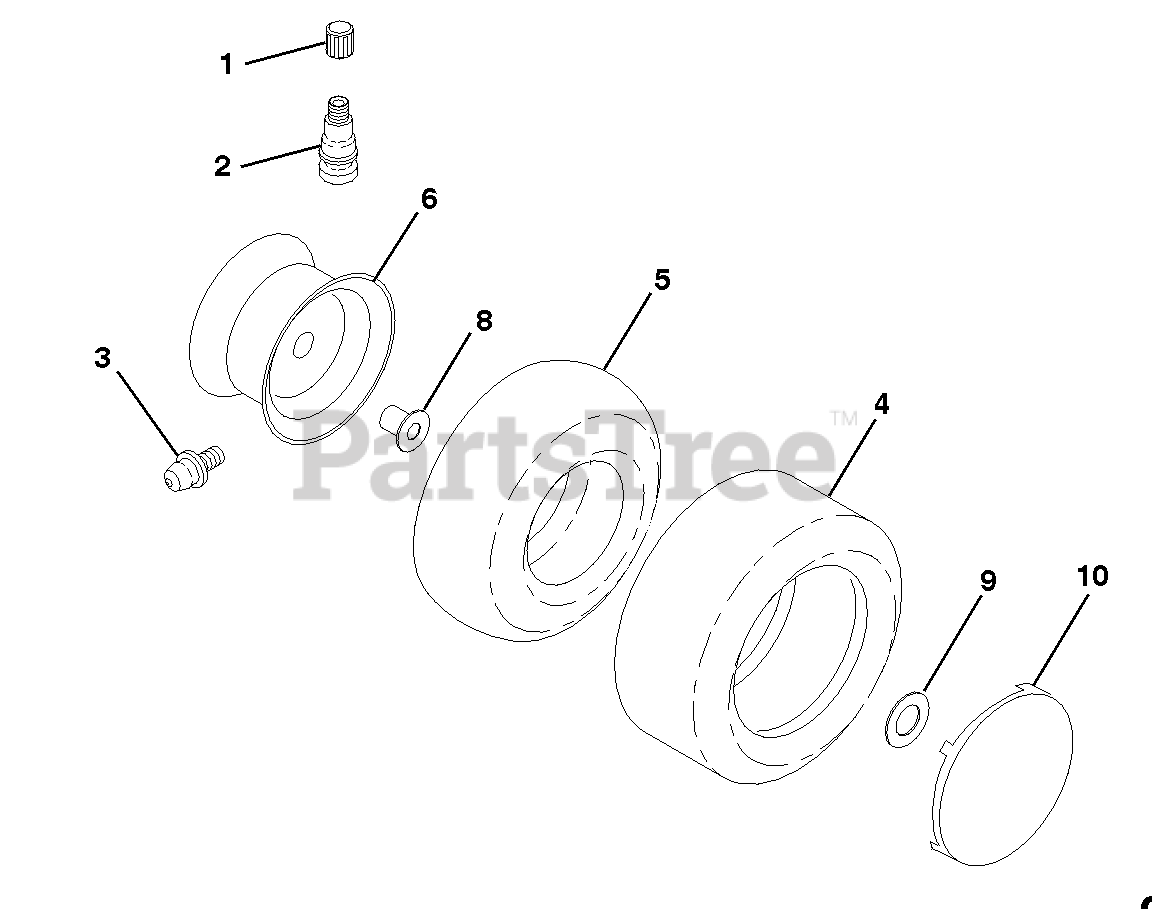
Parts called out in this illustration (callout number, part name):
1	Cap, Valve Stem
2	Stem, Valve
3	Fitting, Grease
4	Tire, Front
4	Tire, Rear
5	Tube, Front Tire
5	Tube, Rear Tire
6	Rim, Front
8	Bearing Flange
9	Washer 25/32 x 1-5/8 x 16 Gauge
10	Cover, Wheel, Front, 6"
10	Cover, Wheel, Rear, 8"
